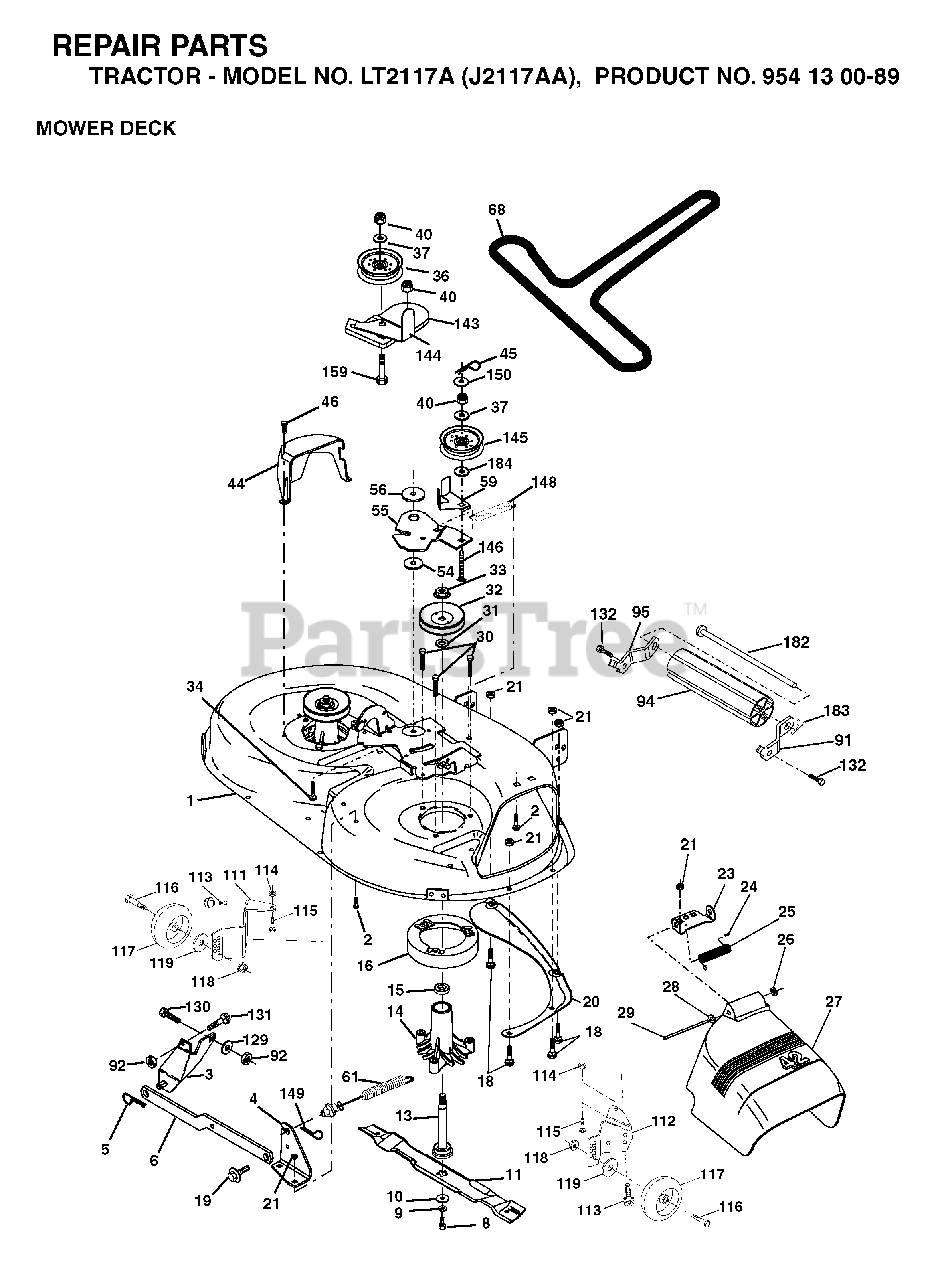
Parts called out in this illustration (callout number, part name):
1	42" DECK KIT
2	BOLT
3	BRKT ASM SWAY BAR
4	BRACKET SWAY BAR 42" DECK
5	RETAINER-SPRNG RB
6	BAR SWAY DECK
8	BLADE BOLT
9	LOCKWASHER
10	WASHER.BLADE
11	BLADE 42"
13	SHAFT ASM VENT
14	HSG MANDREL
16	STRIPPER, MWR ROUND
18	BOLT
19	BOLT SHD 5/16-18
20	BAFFLE.VORTEX
21	LOCKNUT
23	BRKT, DEFL. MOWER
24	CAP-SLEEVE LT
25	SPRING TORSION
26	NUT PUSH M
27	SHIELD DEFLECTOR
28	WASHER
29	ROD.HINGE
30	SCREW, WASHER HEAD
31	WASHER
32	PULLEY/MANDREL
33	NUT, FLG TOPLOCK 9/16"
34	BOLT
36	FLAT IDLER PULLEY
40	LOCKNUT
44	GUARD MANDREL LH BLACK
45	RETAINER M
46	SCREW.1/4-20X5/8
55	ARM IDLER 42" MOWER LT/YT
56	SPACER.RETAINER.MOWER
59	GUARD, BELT
61	SPRING EXT ELEC CLUTCH
91	BRACKET ASM NOSEROLLER LH
92	NUT
94	NOSE ROLLER
95	BRACKET ASM NOSEROLLER RH
111	BRACKET, WHEEL
112	BRACKET, WHEEL
113	SCREW.3/8-16X.625
114	NUT
115	BOLT
117	WHEEL.GAUGE.STANDARD
118	LOCKNUT
119	WASHER
129	WASHER
131	BOLT D
132	SCREW, 3/8-16X3/4
143	BRACKET, ARM IDLER
144	KEEPER.BELT.42".CLUTCH.CABLE
145	PULLEY
146	BOLT, CARRIAGE IDLER BLACK
148	IDLER RETURN SPRING
149	SPRING.RETAINER.YELLOW.ZINC
150	WASHER PM
159	BOLT
182	ROD ROLLER NOSE STANDARD
183	SPRING RETAINER
184	WASHER
